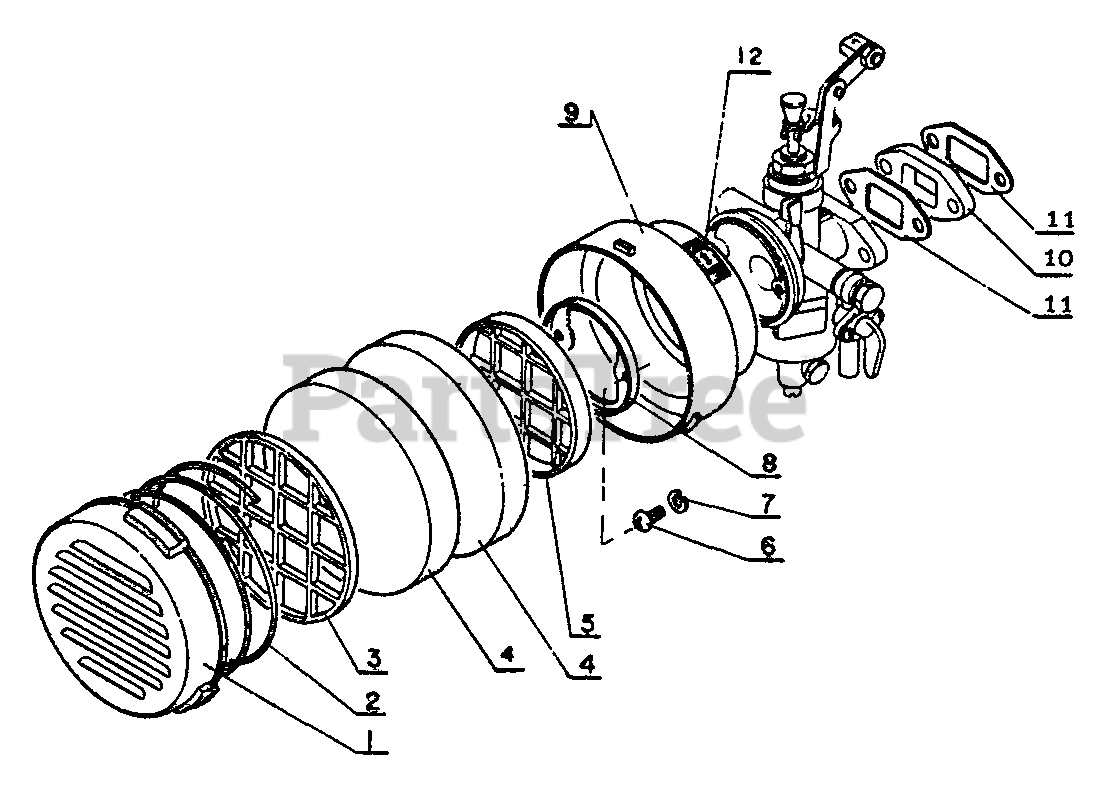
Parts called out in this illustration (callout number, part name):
1	COVER, AIR FILTER
3	RETAINER, AIR FILTER
4	FILTER, AIR
5	RETAINER, AIR FILTER
6	SCREW - 4X12
7	LOCKWASHER - 4
8	BRACKET, AIR CLEANER
9	CASE, AIR FILTER
10	INSULATOR, INTAKE
11	GASKET, INTAKE
12	LABEL - CHOKE
